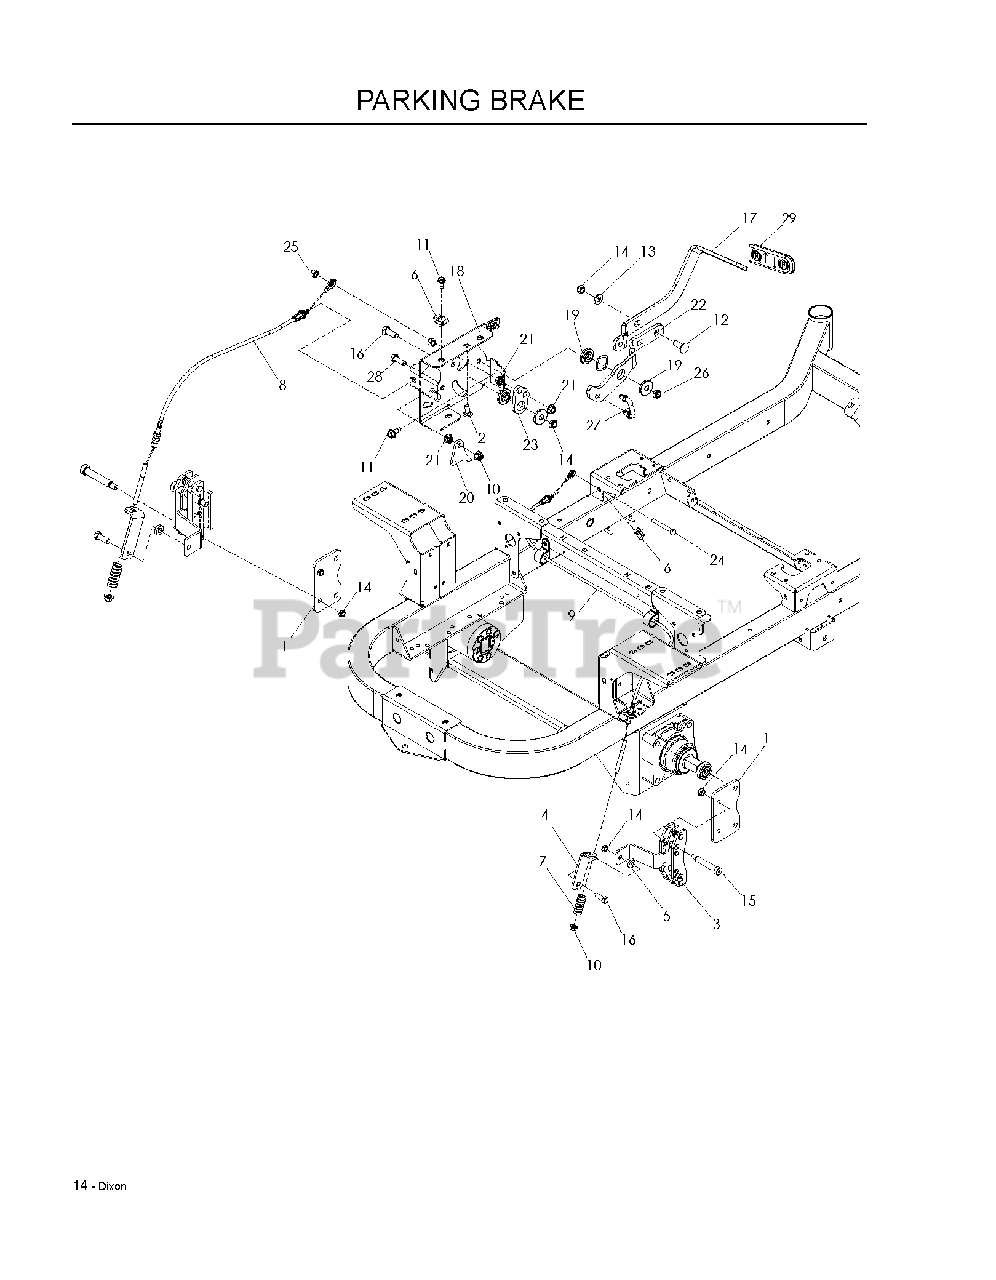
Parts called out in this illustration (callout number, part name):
1	PLATE, BRAKE
2	BOLT 5/16C X 3/4" CARRIAGE
3	CALIPER
4	BRACKET, L
5	WASHER 3/8 X 3/4 X .187 TK
6	U-CLIP 5/16-18 NUT RETAINER
8	CABLE, BRAKE, SHORT
9	CABLE, BRAKE, LONG
10	5/16-18 NYLOC FLANGE NUT
11	BOLT 5/16-18 X 3/4
12	RHSNB 3/8C X 1
13	WASHER 3/8 SAE FLAT
14	NUT HEX 3/8-16 NYLON, THIN
15	SB 3/8-16 X 2-1-1/2 SKT HDD ZD
16	HCS 3/8C X 1
17	ARM, BRAKE, BLK
18	MOUNT, BRAKE WLDMT
19	BUSHING, BRAKE
20	ACTUATOR, SWITCH
21	NUT 5/16C WHIZ
22	LEVER, BRAKE
23	BELLCRANK, BRAKE
24	HCS 5/16-18 X 2 1/2 TPBLT
25	NUT 5/16 NYLOC
26	NUT HEX 3/8-16 NYLON, THIN
27	LINKAGE, BRAKE
28	HCS 5/16C X 1
29	GRIP BRAKE HANDLE
